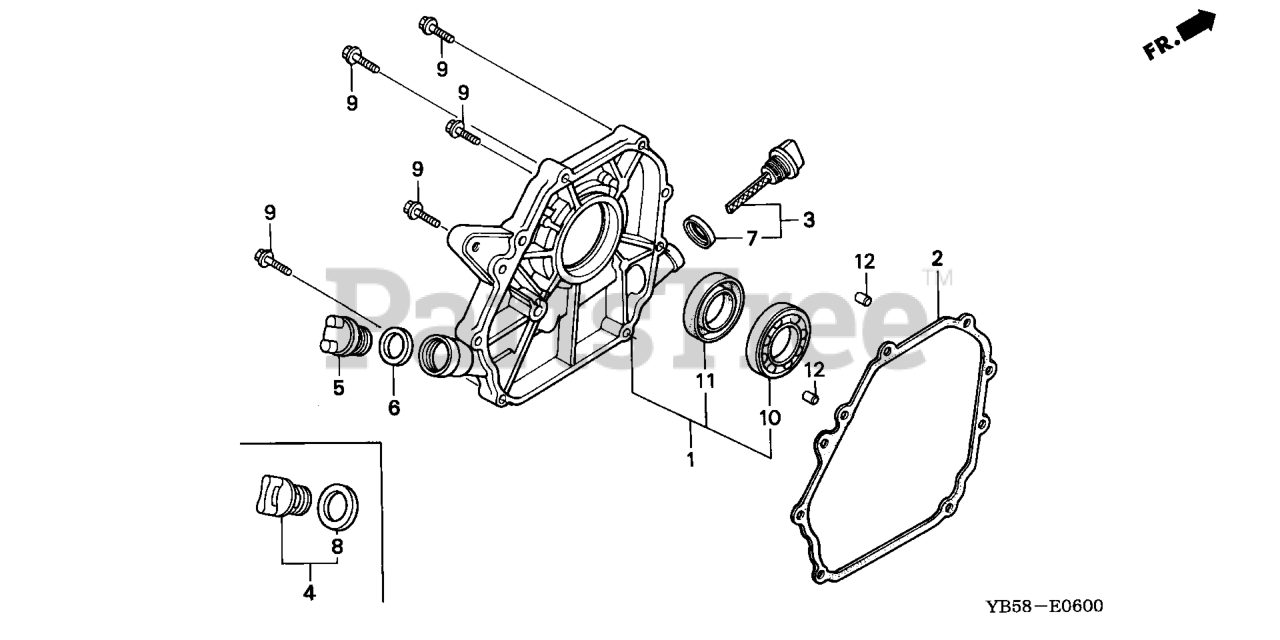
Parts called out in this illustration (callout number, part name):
1	COVER ASSY., CRANKCASE
2	GASKET, CASE COVER
3	CAP ASSY., OIL FILLER
4	CAP ASSY., OIL FILLER
7	GASKET, OIL FILLER CAP
8	GASKET, OIL FILLER CAP
9	BOLT, FLANGE (6X28) (CT200) Use up to Engine SN 1530314.
10	BEARING, RADIAL BALL (62/22)
11	OIL SEAL (22X41X6)
12	PIN A, DOWEL (8X14)
